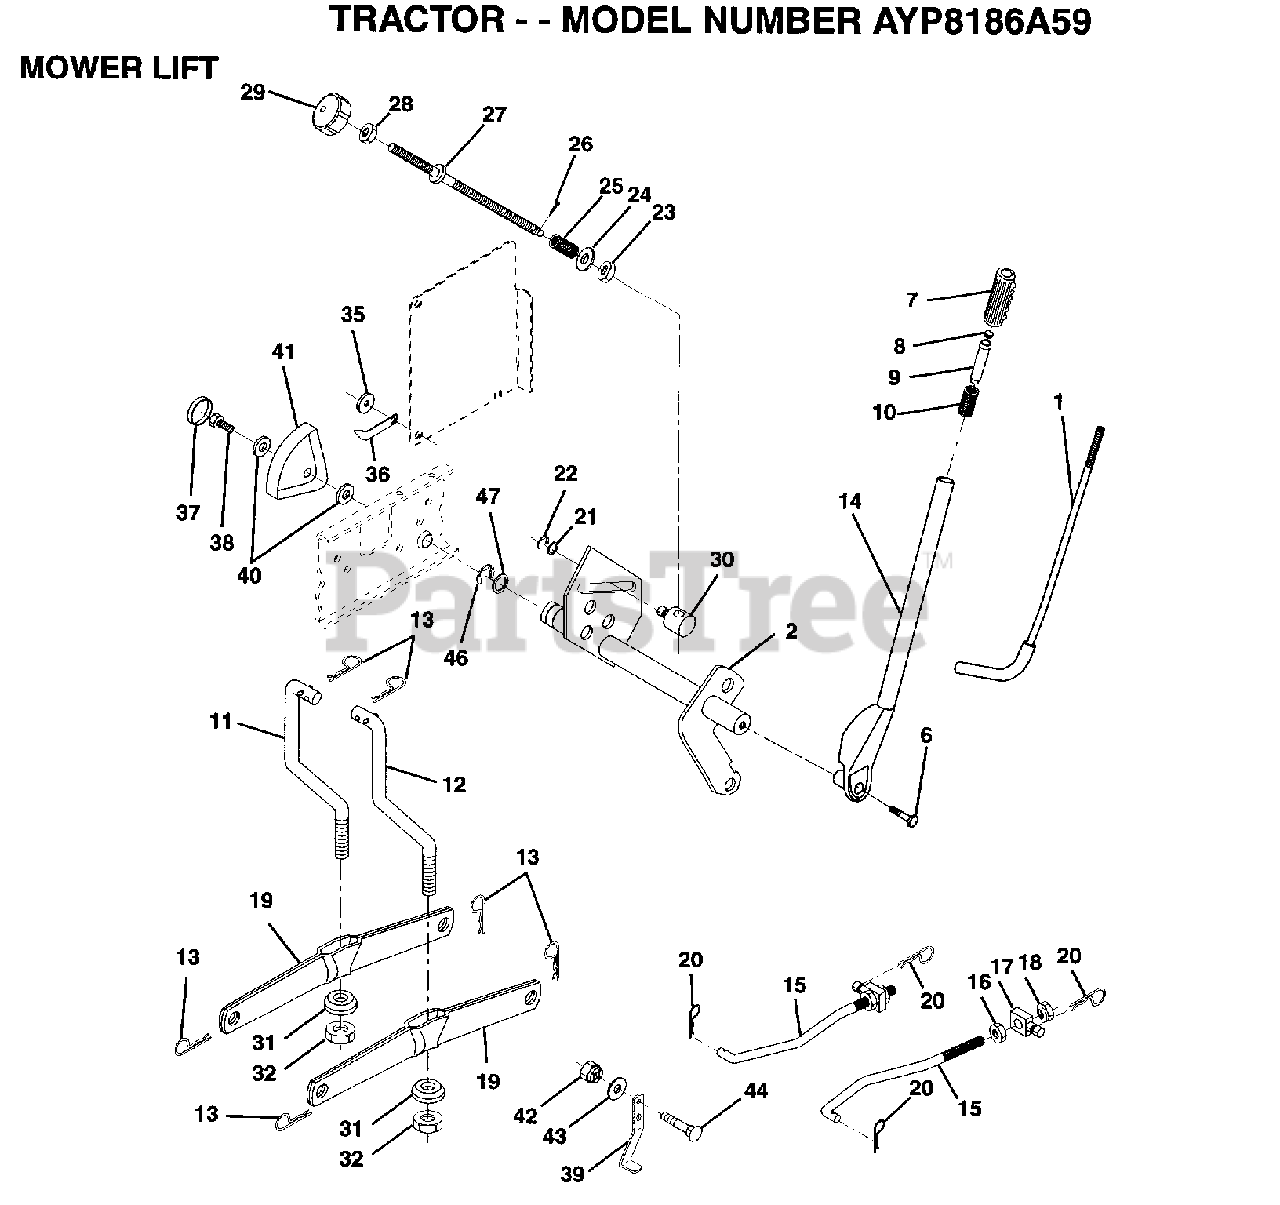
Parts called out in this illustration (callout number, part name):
1	LEVER ROD LT
2	SHAFT LIFT W/IND
6	"BOLT,HEX"
7	GRIP HANDLE
10	SPRING T
11	LINK.LIFT.LH.GTV
12	LINK.LIFT.RH.GTV.
15	LINK.FRONT
16	NUT
17	TRUNION
18	NUT.LK.W/WSH.1/2.
19	ARM SUSP REAR
20	RETAINER.SPRING
21	WASHER
22	KLIP RING
23	NUT T
24	WASHER
25	SPRING.COMP.INF.H
27	ROD.ADJ.LIFT
28	NUT
29	KNOB INF 3/8-16
30	TRUNION LT
31	BEARING PVT LH
32	NUT.CROWNLOCK.3/8
35	WASHER T
36	POINTER HGT IND
37	"PLUG,HOLE"
38	SCREW
39	STOP.OVER.CENTER
40	WASHER
41	HEIGHT INDICATOR
43	WASHER GT
44	BOLT
46	E-RING
47	WASHER
